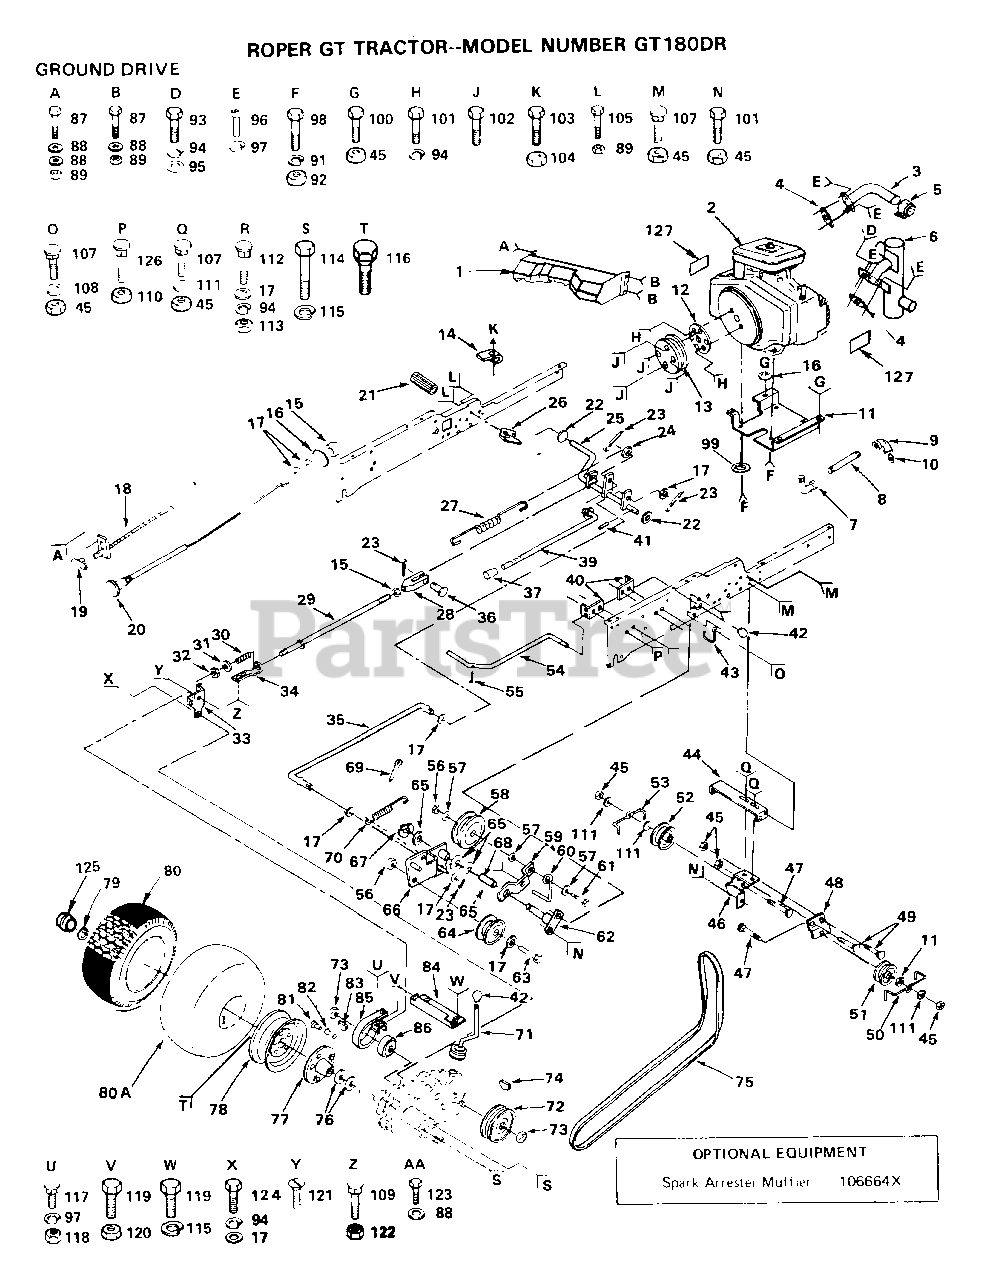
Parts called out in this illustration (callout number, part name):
1	BAFFLE ASSY - ENGINE
3	EXHAUST TUBE T
5	CLAMP-TUBE GTV
11	"ENGINE GT, BASE"
12	ADAPTER T
14	ACT-SWITCH T
16	LOCKWASHER
17	WASHER
18	THRTL CONTROL T
21	PEDAL COVER T
24	WASHER M
25	SHAFT ASSY GT
26	BRKT SWITCH GT
27	EXT SPRING GT
28	YOKE GTV
29	BRAKE ROD T
30	SPRING T
31	WASHER
33	BRAKE BRKT ASSY T
34	GUIDE ROD T
35	ROD CLUTCH GTV
36	CLEVIS PIN T
37	PLUNGER CAP T
40	ROD BRACKET GT
41	ROLL PIN STD
43	BELT RETAINER GT
44	BRACKET-DRIVE GT
46	BRKT-V-PULLEY GT
47	BOLT
49	BOLT
51	IDLER-FLAT T
52	PULLEY V IDLR GTV
53	ROD SHIFT GTV
56	LOCKNUT
57	WASHER
60	BELT RETAINER GT
62	BRACKET ASSY GTV
65	WASHER T
66	CLUTCH BRACKET GT
67	KLIP RING
68	"GTV, BEARING"
69	COTTER PIN
70	SPRING GTV
71	GEAR SHFT LVR T
72	PULLEY GT
73	NUT STD
75	GEAR 28T T
76	WASHER T
79	KLIP RING
80A	TUBE.23X8/10-12
81	VALVE CAP
82	VALVE STEM LT
86	BRAKE DRUM T
88	WASHER
91	LOCKWASHER
92	NUT.HEX.5/16-18
93	BOLT
94	LOCKWASHER
95	WASHER
97	LOCKWASHER
98	BOLT
99	LOCKWASHER.5/16.E
101	BOLT
103	SCREW
105	BOLT LT
107	BOLT D
108	WASHER
111	WASHER GT
113	NUT.HEX.3/8-16UNC
114	BOLT
115	LOCKWASHER
117	BOLT T
119	BOLT
120	NUT GTV
121	SCREW
123	SCREW
125	CAP-HUB GT
126	BOLT
